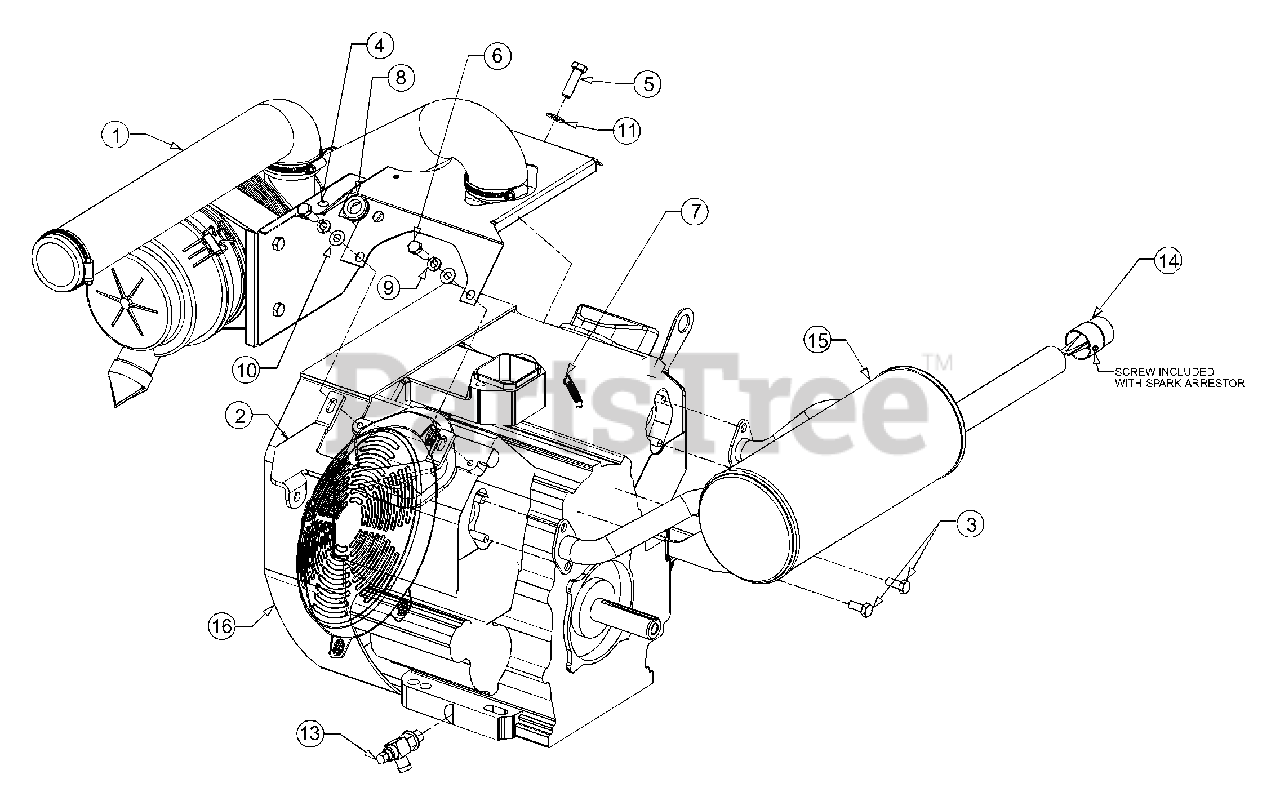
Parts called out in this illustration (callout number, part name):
1	Hose, Air Cleaner Intake
2	Support, Upper Transmission
3	Hex Screw, M8-1.25
4	Screw, Machine #10-24 x .50
5	Hex Screw, 3/8-16 x 1.25
6	Hex Screw, M8-1.25 x 25, Gr8
7	Spring, Extension, .315 OD x 2.125
8	Grommet, Rubber .66 ID x 1.25 OD
9	Washer, Lock, 5/16
10	Washer, Flat, .33 x .678 x .030
11	Washer, Flat, .406 x .812 x .051
13	Valve, Oil Drain
14	Arrestor, Spark 1-1/4
15	Muffler, Honda GXV
16	Engine,Honda GX620K1
